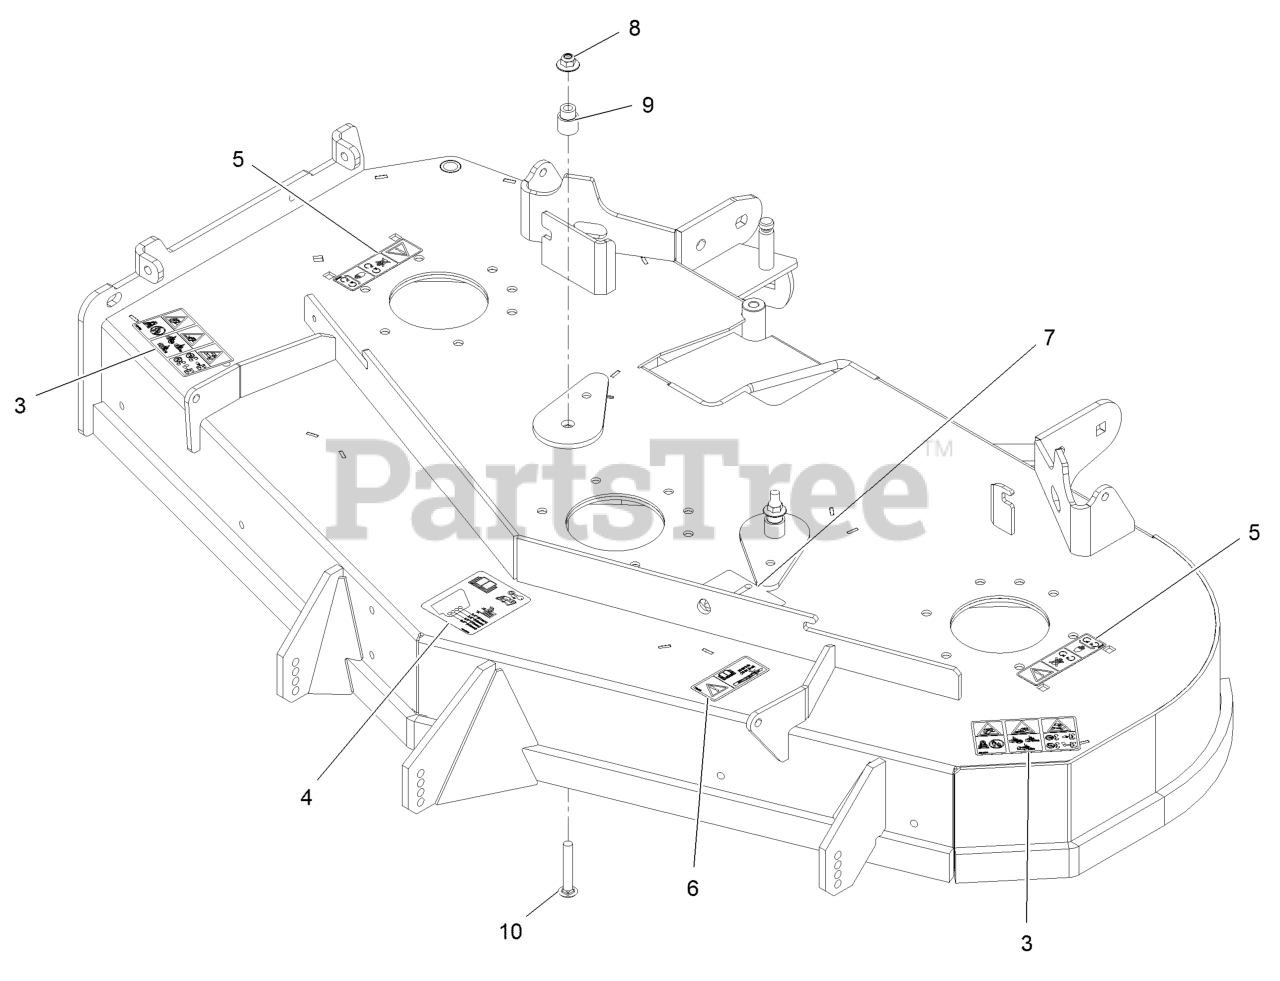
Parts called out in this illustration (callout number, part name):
3	Decal-Danger Thrown Objects
4	Decal-Roller, Anti-Scalp
5	Decal-Missing, Cover
6	Decal-Bolt Torque
7	Decal-Belt Routing
8	Nut-Nyloc 3/8-16 Flg
9	Bushing, Idler
10	Bolt-Carriage 3/8-16 X 2 1/2
